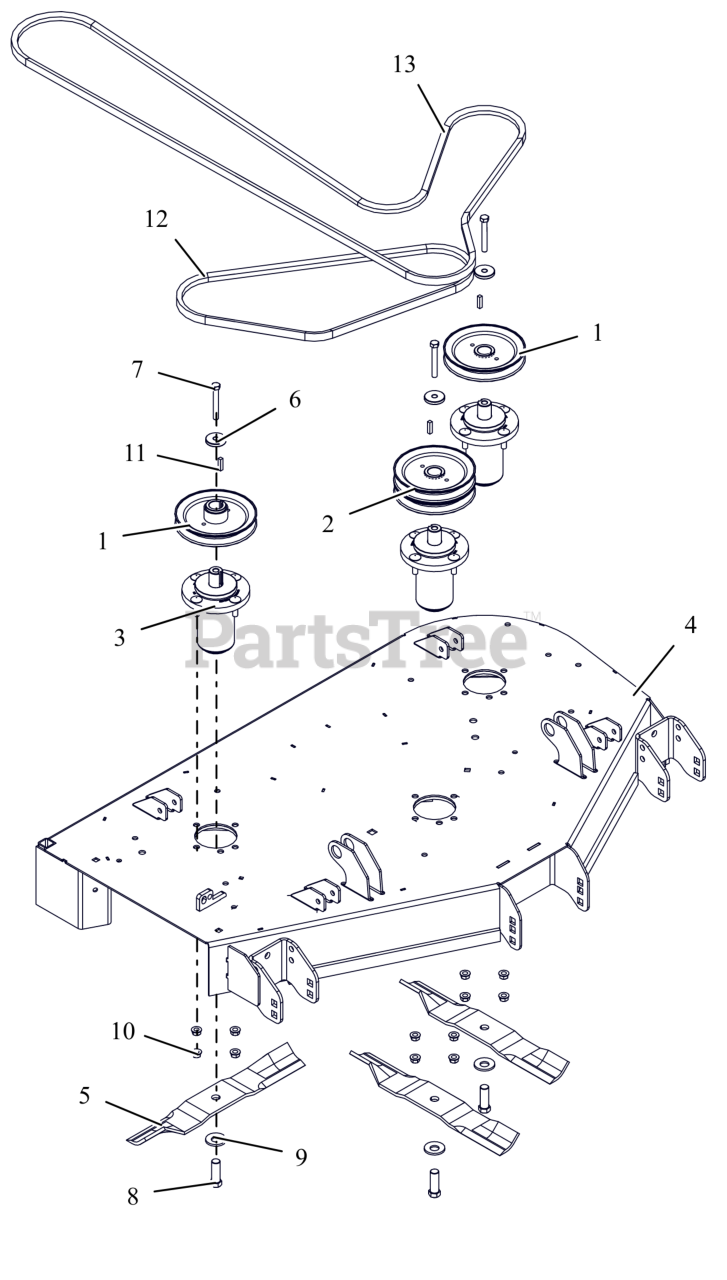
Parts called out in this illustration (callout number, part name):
1	PULLEY, SINGLE-1"ID X 6" OD
2	PULLEY, DOUBLE
3	ASM, MAINT FREE ALUM SPINDLE
4	KIT,DECK-44" W/DECALS -GRAVELY
5	BLADE, 16.19" MOWER (HI-LIFT)
6	RETAINER, SHEAVE
7	BLT, HEX .38-16X2.75 G8 ZCC
8	BLT, HEX .62-18X1.75 G8 ZCC
9	WSHR-BLVL .669X1.535X.138
10	NUT-LK-CTR-FLG .375-16 GF ZCC
11	KEY, SQ .25X.25X1.00 RC 40-50
12	V-BELT, B-COGGED
13	V-BELT, HB RAW EDGE EPDM
